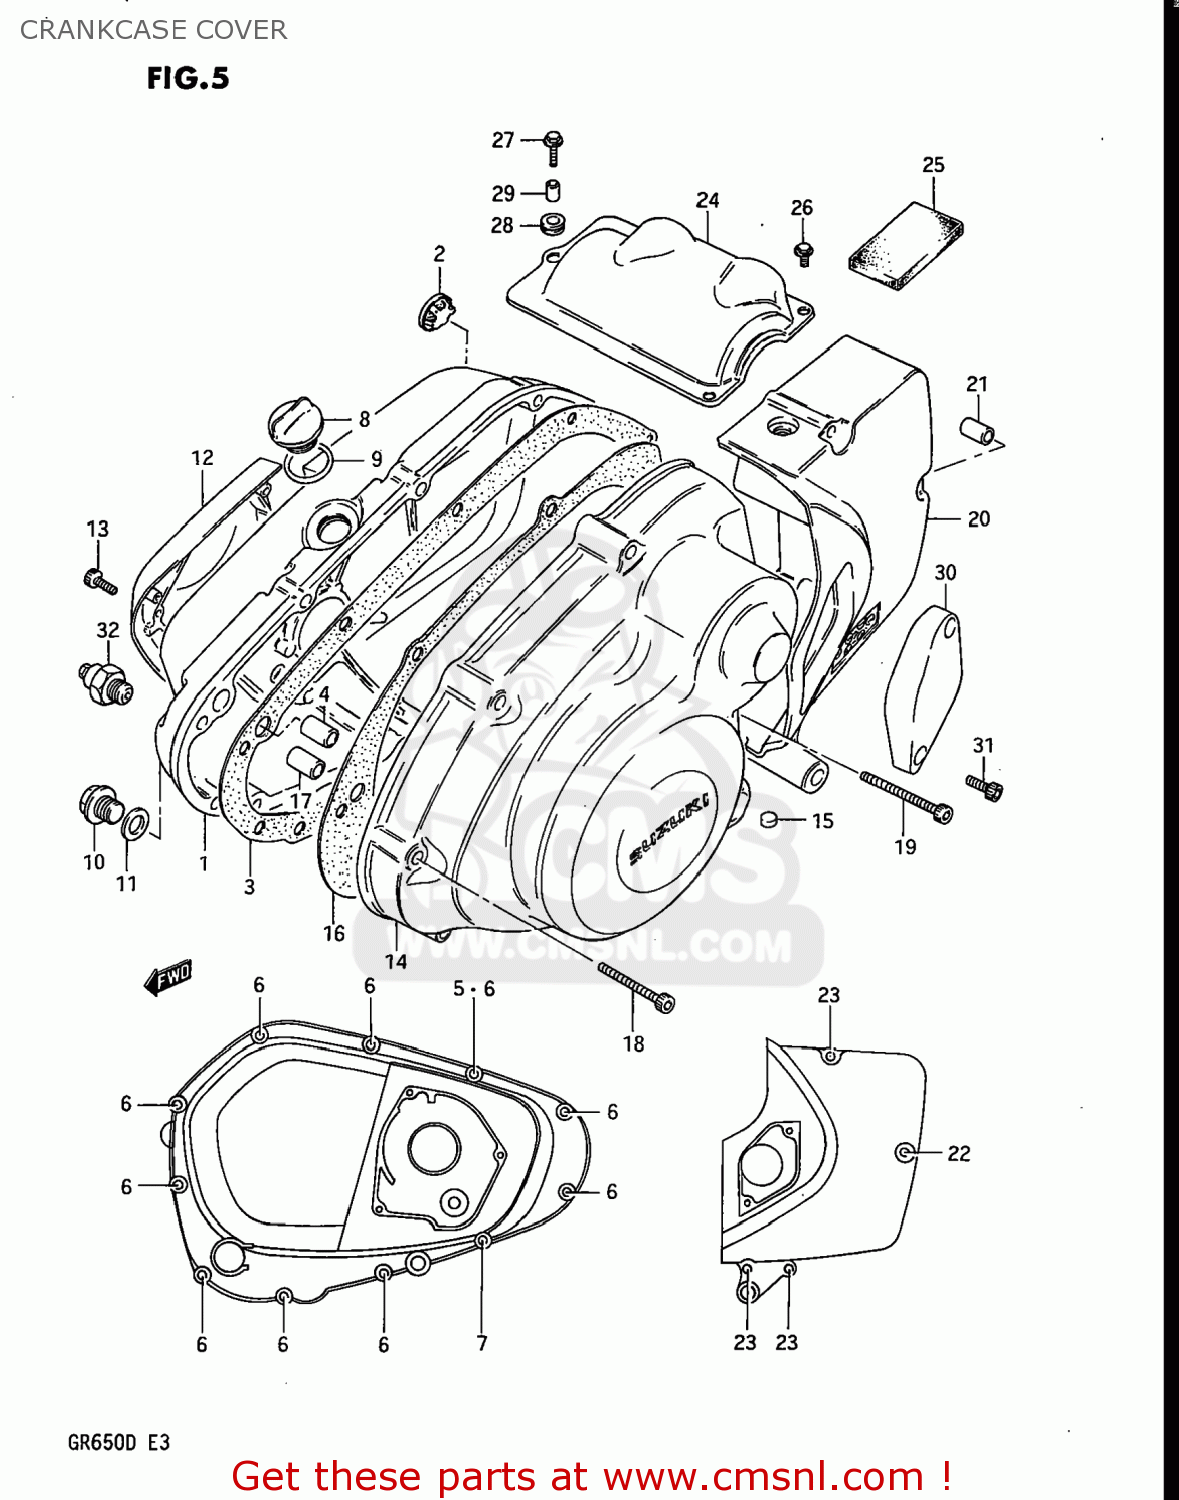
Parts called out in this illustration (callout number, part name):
1	COVER,CLUTCH
2	LENS,OIL LEVEL CHECK
3	GASKET,CLUTCH COVER (MCA)
4	PIN (11X20)(SUS)
5	GASKET (NAS)
6	BOLT (6X30)
7	BOLT (6X40)
8	PLUG(20X10)
9	O RING(D:3.1,ID:16.8)
10	PLUG (14X12)
11	GASKET(14X19.2X2) (NAS)
12	COVER,CONTACT BREAKER
13	BOLT
14	COVER,MAGNETO
15	MAGNETO
16	GASKET,MAGNETO COVER
17	PIN (11X20)(SUS)
18	BOLT (6X40)
19	BOLT (6X50)
20	COVER,ENGINE SPROCKET
21	PIN
22	BOLT (6X65)
23	BOLT (6X50)
24	COVER,STARTER MOTOR
25	DAMPER,STARTER MOTOR CLUTCH
26	BOLT (5X8)
27	BOLT 5X16
28	CUSHION
29	SPACER (5.2X9X5)
30	CAP,CLUTCH RELEASE ADJUST
31	BOLT
32	SWITCH ASSEMBLY
